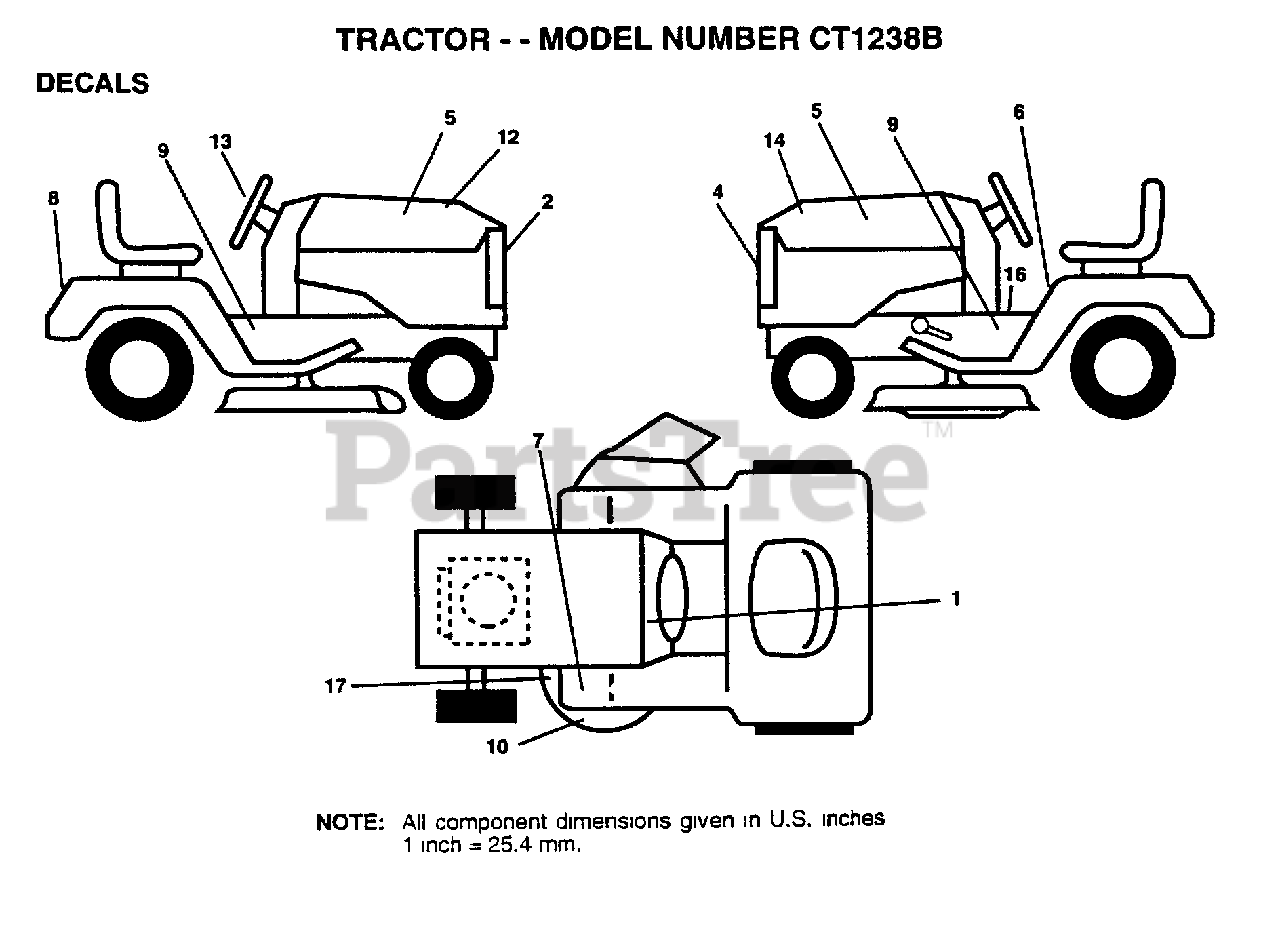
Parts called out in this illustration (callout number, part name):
1	DECAL.DASH.INST.
2	GRILL DECAL
5	DECAL.HOOD.INS.
6	DECAL
8	FENDER DECAL
9	DECAL CHASSIS SPEED DECK
12	DECAL HOOD RH RLY
13	"DECAL,STR WHL"
14	DECAL HOOD LH RLY
16	DECAL BRAK PARK
17	DECAL
